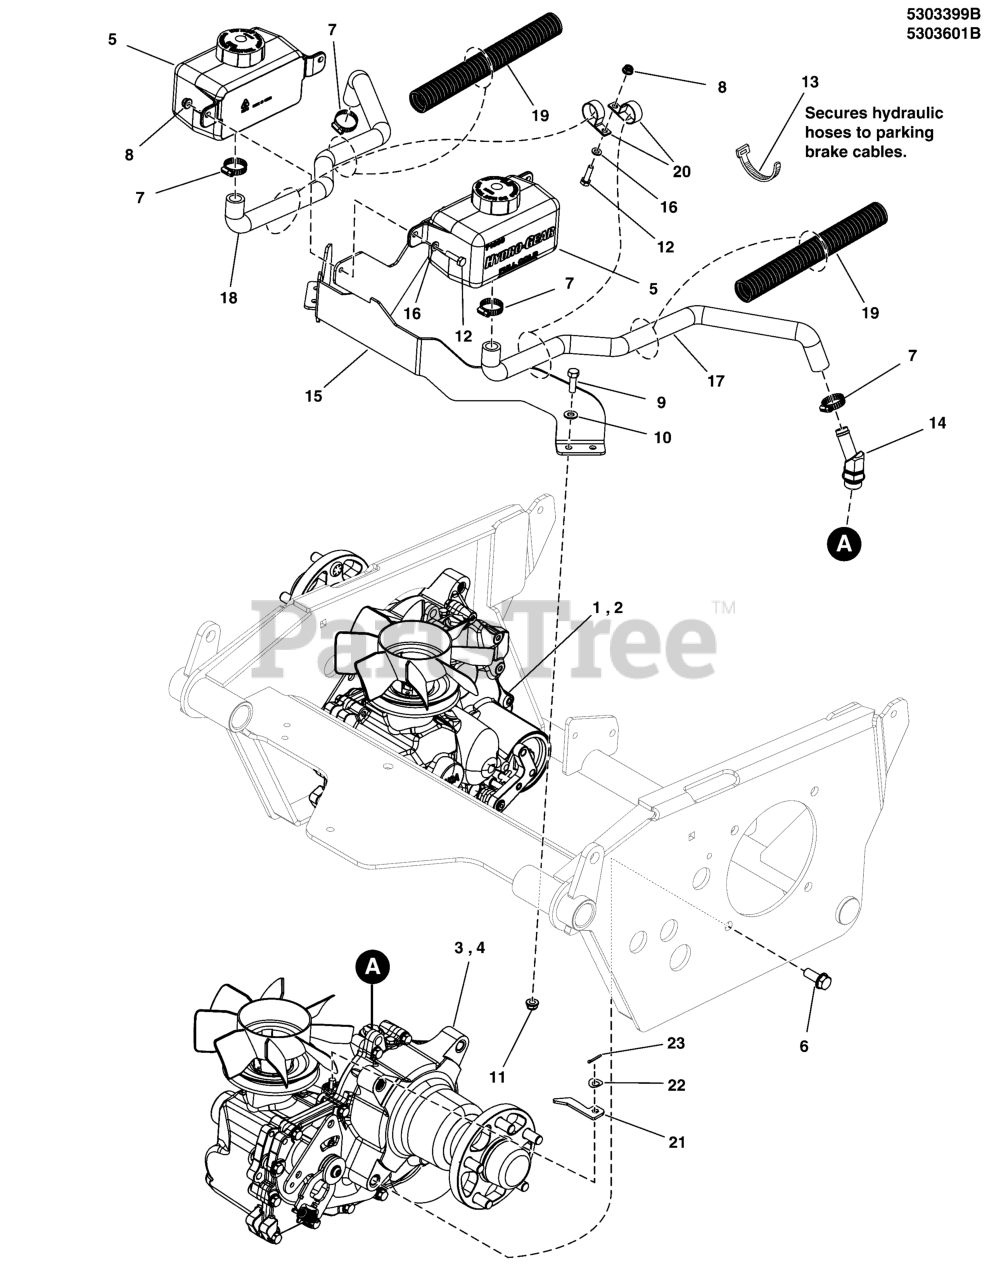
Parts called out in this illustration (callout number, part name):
1	TRANSAXLE
2	TRANSAXLE
3	TRANSAXLE
4	TRANSAXLE
5	HYDRO TANK, HYDRO-GEAR 71938, 1 LITER
6	BOLT, 1/2-13 X 1-1/4, SF, PLT W/PATCH
7	CLAMP, #10 HOSE, STAINLESS
8	NUT, 1/4-20 HEX NYLOCK FLANGE
9	BOLT, 5/16-18 X 1 GD5 CZ
10	WASHER, 5/16" SAE
11	NUT, 5/16-18 HEX NYLOCK FLANGE
12	BOLT, 1/4-20 X 1" GD5 CZ
13	TIE,SELF-LOCKING, 6"
14	FITTING 22.5 ELBOW5/8 TUBE-7/8-14 O-RING
15	MOUNT, Tank
16	WASHER, 1/4 SAE
17	HOSE, HYD RES, LH, IS2100Z
18	HOSE, HYD RES, RH, IS2100Z
19	LOOM, CONVOLUTED SPLIT, 1 ID - 13 LONG
20	CLAMP, VINYL INSULATED, 1.00
21	ARM, TRANSAXLE RELEASE, ZT4400
22	WASHER,WAVE,M10
23	PIN, 3/32 X 0.750, COT, ZINC/CLEAR
